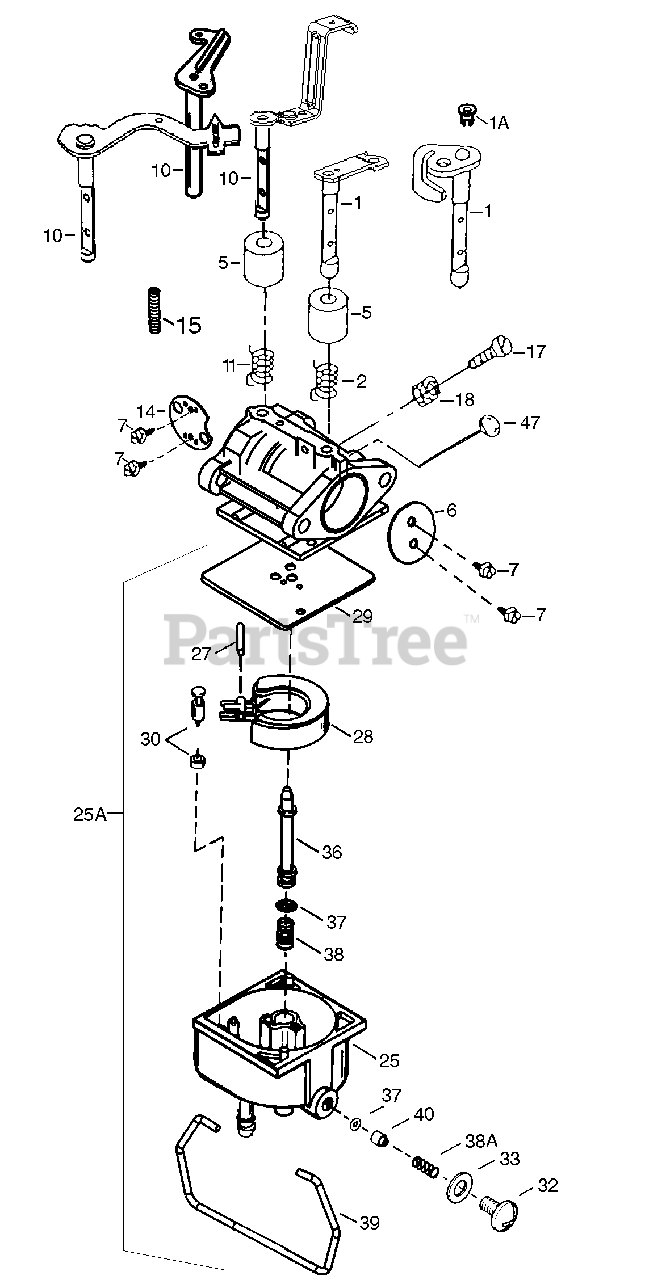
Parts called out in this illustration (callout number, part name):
1	Throttle Shaft & Lever Assembly
1A	Throttle Link Bushing
2	Throttle Return Spring
5	Dust Seal
6	Throttle Shutter
7	Throttle Shutter Screws
10	Choke Shaft & Lever Assembly
11	Choke Return Spring
13	Dust Seal
14	Choke Shutter
17	Throttle Crack Screw/Idle Speed Screw
18	Tension Spring
25	Float Bowl Assembly
25A	Float Bowl Assembly Repair Kit
27	Float Shaft
29	Float Bowl to Body Gasket
30	Inlet Needle & Seat
32	Bowl Drain Screw
33	Bowl Drain Washer
36	Main Nozzle Tube
37	"O" Ring, Main Nozzle Tube
37A	"O" Ring
38	Spring, Main Nozzle Tube
39	Float Bowl Retainer
40	Main Fuel Jet
47	Welch Plug, Idle Mixing Well
